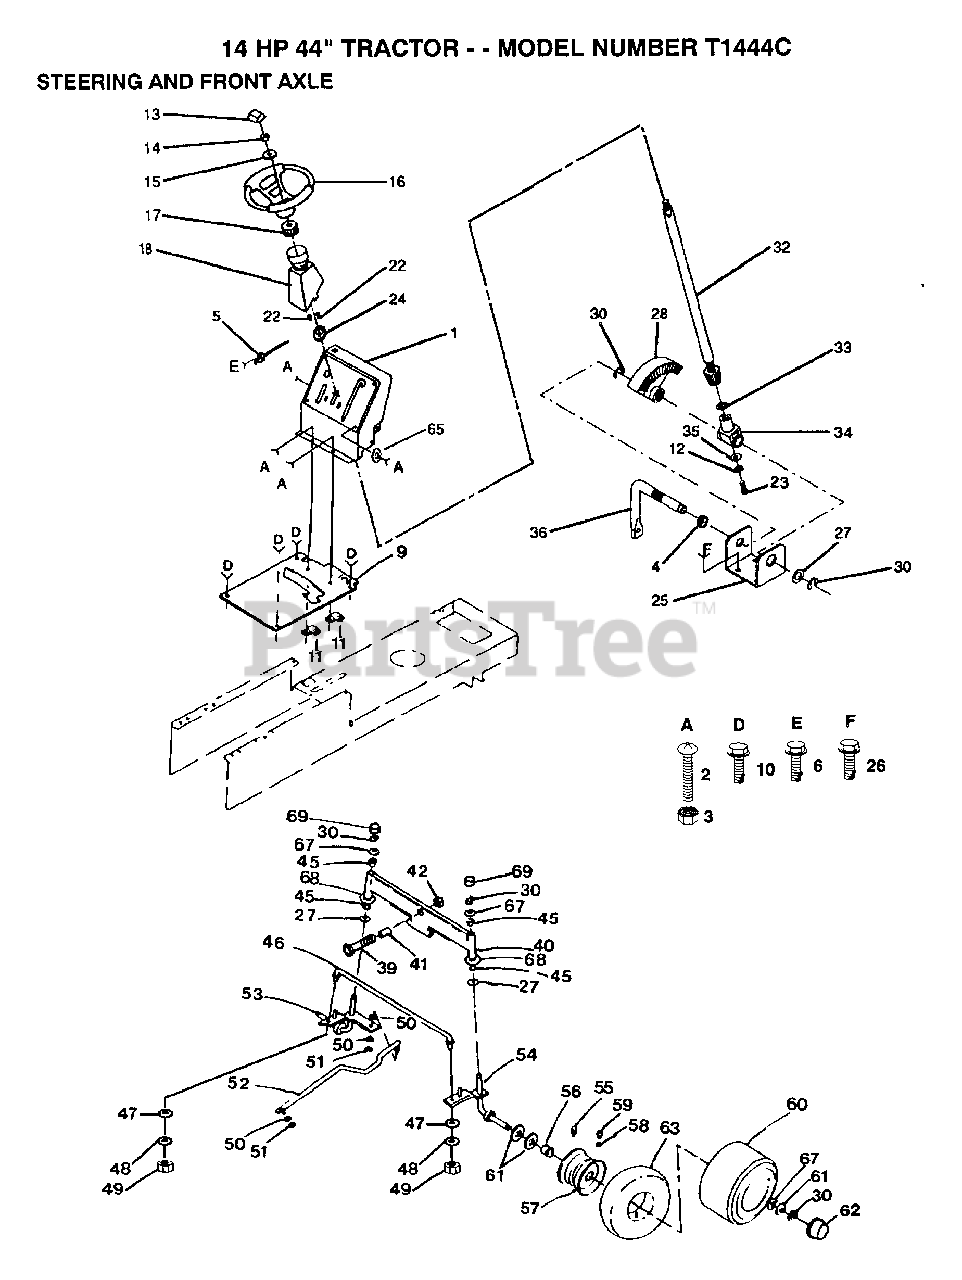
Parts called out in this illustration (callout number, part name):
2	SCREW
4	NYLINER T
6	SCREW LT
10	SCREW LT
11	CLIP T
12	LOCKWASHER
13	INSERT, STEERING WHEEL
14	GRIPCO NUT
15	WASHER T
17	ADAPTER-WHEEL LT
18	"TUBE, STR SHAFT"
23	"SCREW,SPECIAL"
25	"BRKT,STEERING"
26	SCREW
27	WASHER .T
30	RING
33	THRUST WASHER
34	SUPPORT.SHAFT
39	BOLT LT
41	BEARING
45	COL. SRTG. BEAR.
46	TIE ROD
47	WASHER M
48	LOCKWASHER
49	NUT.LOCK.5/16-24
50	LOCKWASHER
54	SPINDLE ASM RH
55	FITTING LT
56	"FLANGE, BEARING"
58	VALVE CAP
59	VALVE STEM LT
61	WASHER
62	HUB CAP
63	TUBE.5.3/4.5/6
65	LOCKWASHER.5/16.E
67	WASHER
68	WASHER
69	CAP
